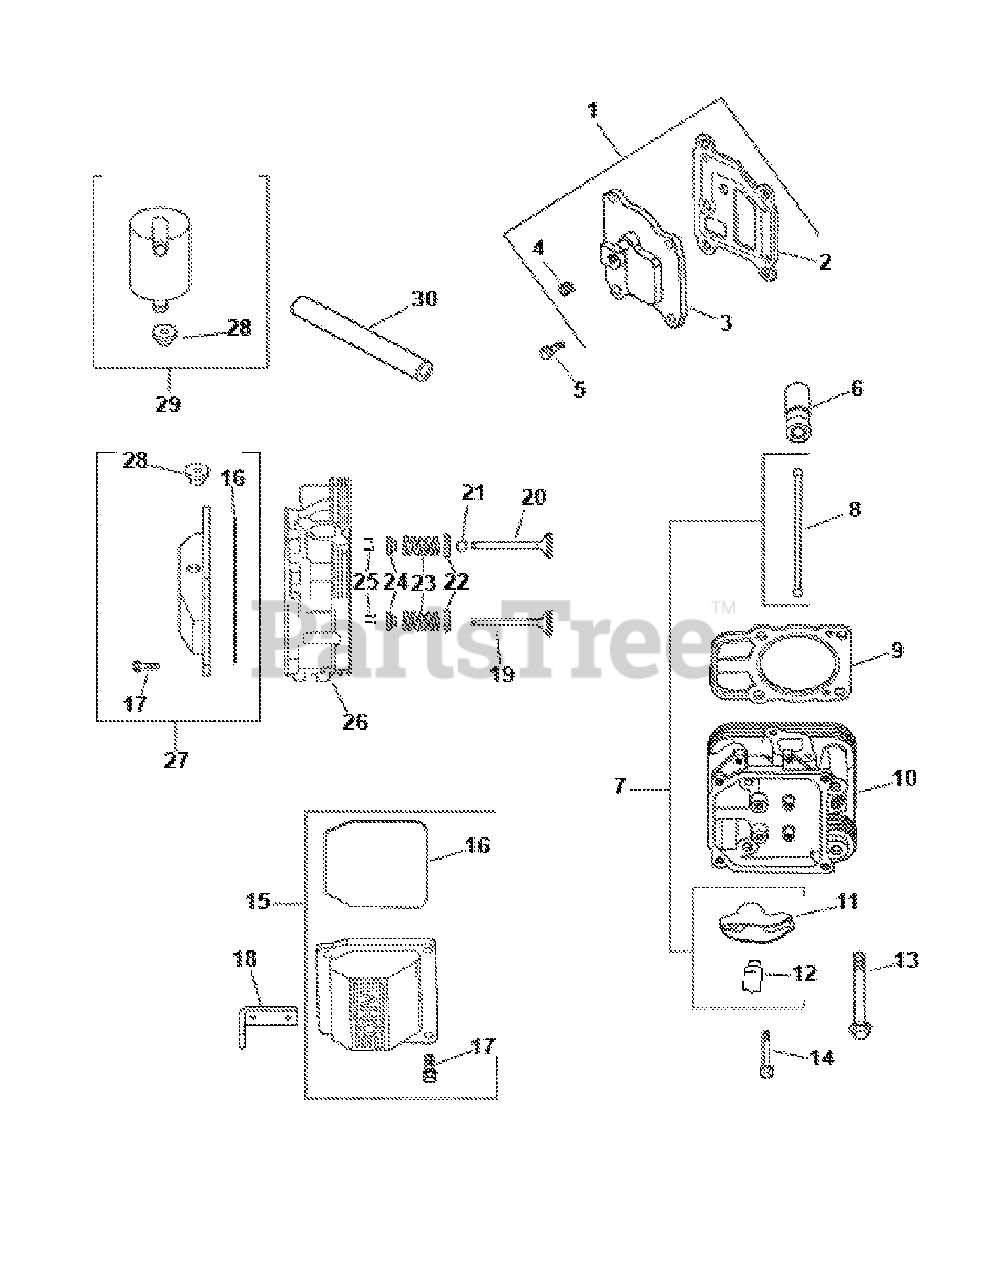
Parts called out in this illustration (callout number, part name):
1	Breather Cover Kit
2	Breather Gasket
3	Breather Cover
4	1/8" Pipe Plug
5	Hex Flange Screw
6	Valve Lifter
7	Valve TrainKit
9	Cylinder Head Gasket
10	Cylinder Head Assembly #2
12	Rocker Arm Pivot
13	Hex Flange Screw
14	Rocker Arm Pivot Screw
15	Rocker Cover Kit
17	Hex Flange Screw
18	Lifting Strap
19	Exhaust Valve
19	Exhaust Valve (.25)
20	Intake Valve
20	Intake Valve (.25)
21	Valve Stem Seal
23	Valve Spring
24	Valve Spring Retainer
25	Retainer Kit
26	Cylinder Head Assembly #1
27	Rocker Cover (Separator) Kit
28	Rubber Grommet
29	Breather Separator Kit
30	Breather Hose
